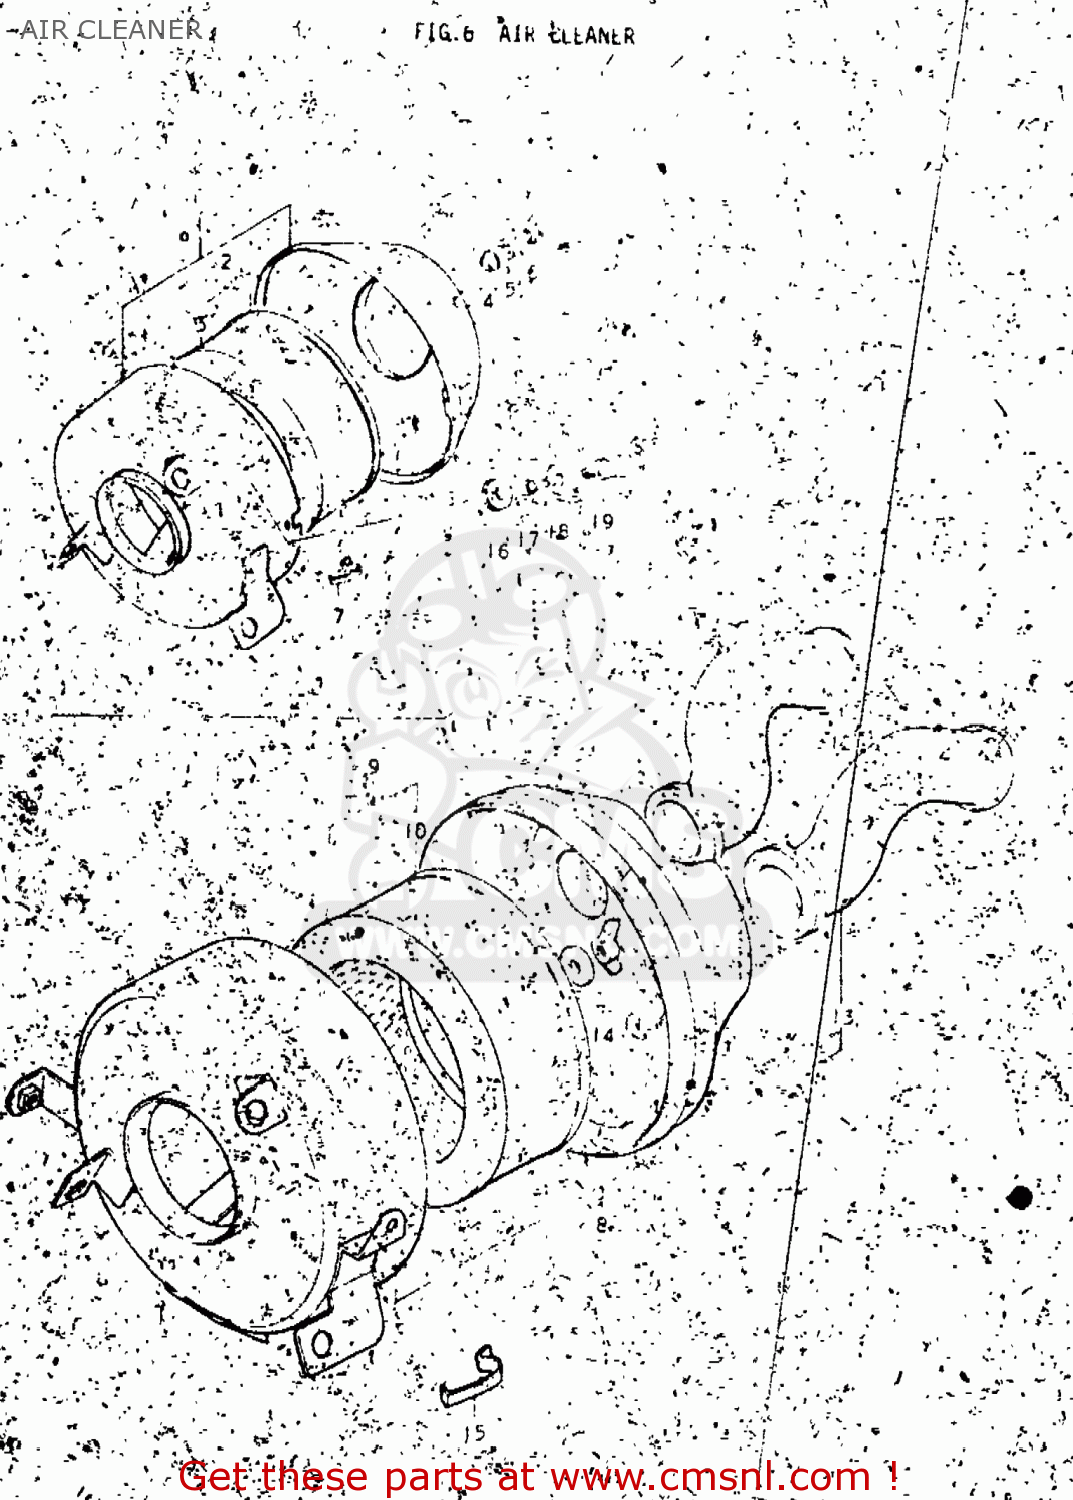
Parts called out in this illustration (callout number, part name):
1	CLEANER ASSEMBLY,AIR
2	FILTER,AIR CLEANER
3	ELEMENT,AIR CLEANER
5	WASHER
6	NUT
7	SPRING,AIR CLEANER
8	CLEANER ASSEMBLY,AIR
9	FILTER,AIR CLEANER
10	ELEMENT,AIR CLEANER
11	NUT
15	SPRING,AIR CLEANER
16	CUSHION
17	SPACER (7X9X7)
18	WASHER (6.5X20X1.2)
19	BOLT
